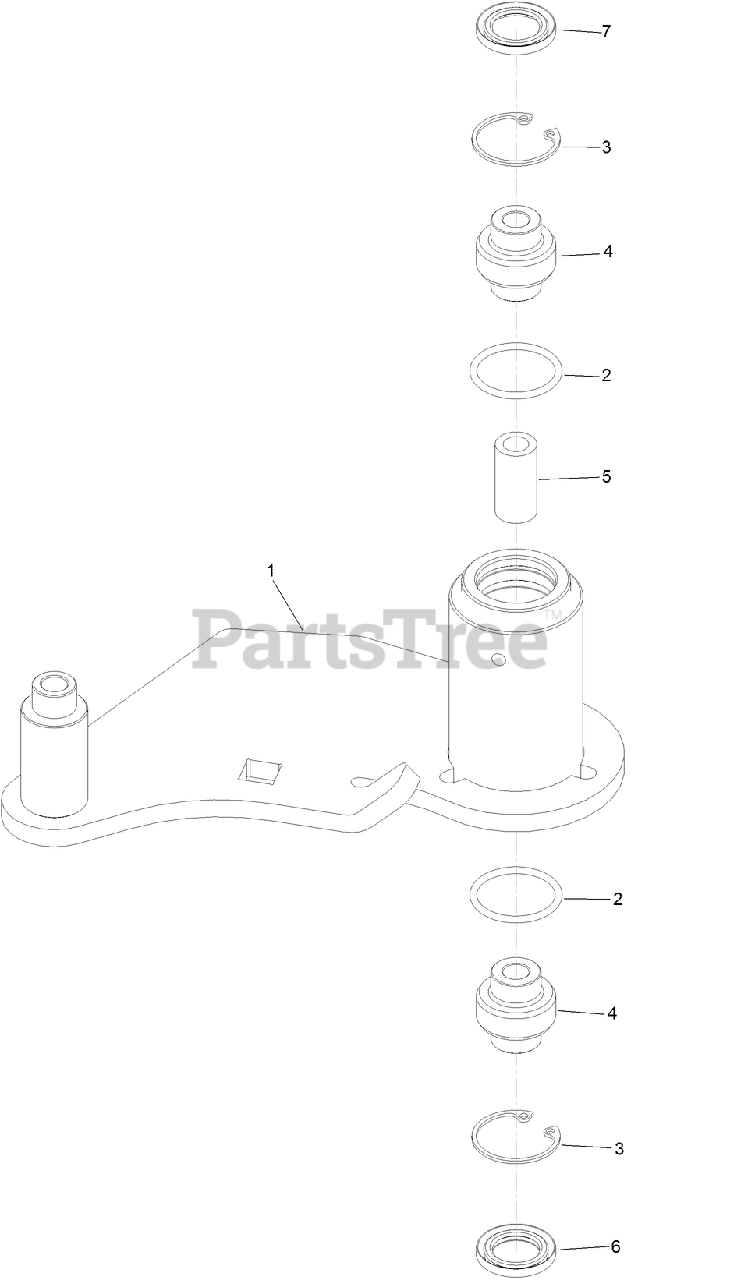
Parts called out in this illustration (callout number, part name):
1	IDLER-DECK
2	O-RING
3	RING-SNAP
4	BEARING-SPHERICAL
5	SPACER
6	SEAL-LIP, DOUBLE
7	SEAL-LIP, SINGLE
